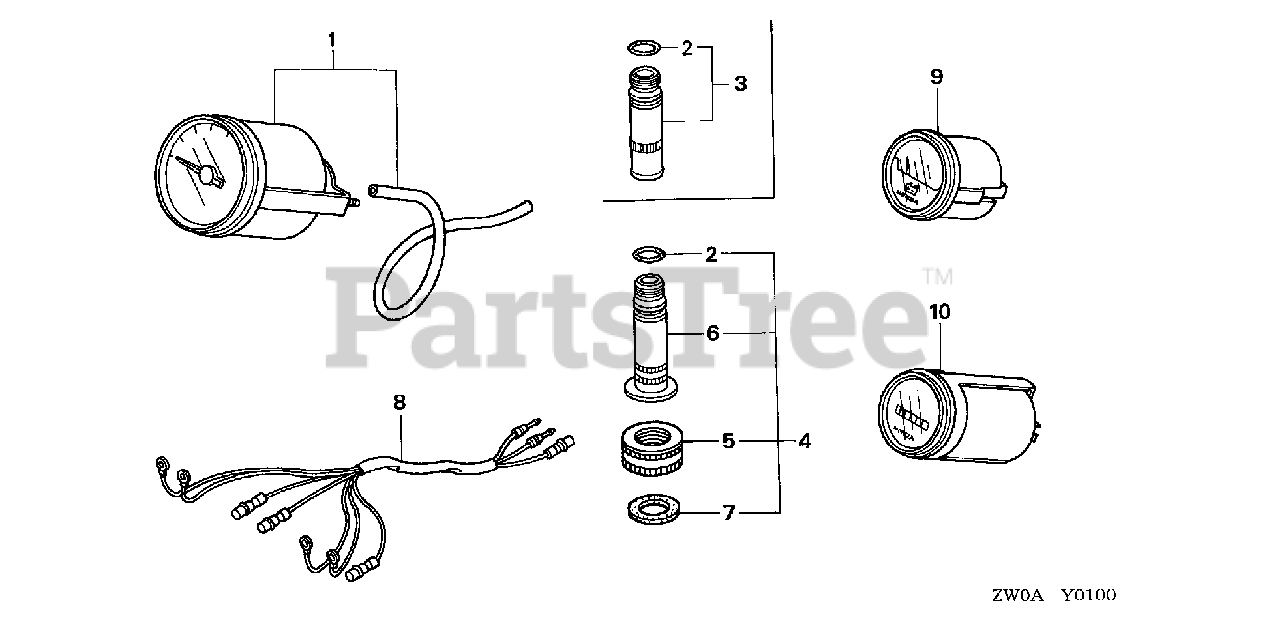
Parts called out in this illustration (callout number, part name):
1	SPEEDOMETER KIT
2	O-RING (11.8X2.4)
4	JOINT ASSY., HOSE
5	NUT, WATER MOUTH
6	JOINT ASSY., HOSE
7	SEAT, WATER MOUTH
8	HARNESS ASSY., METER (B)
9	METER ASSY., VOLT
10	METER ASSY., HOUR L.C.D.
